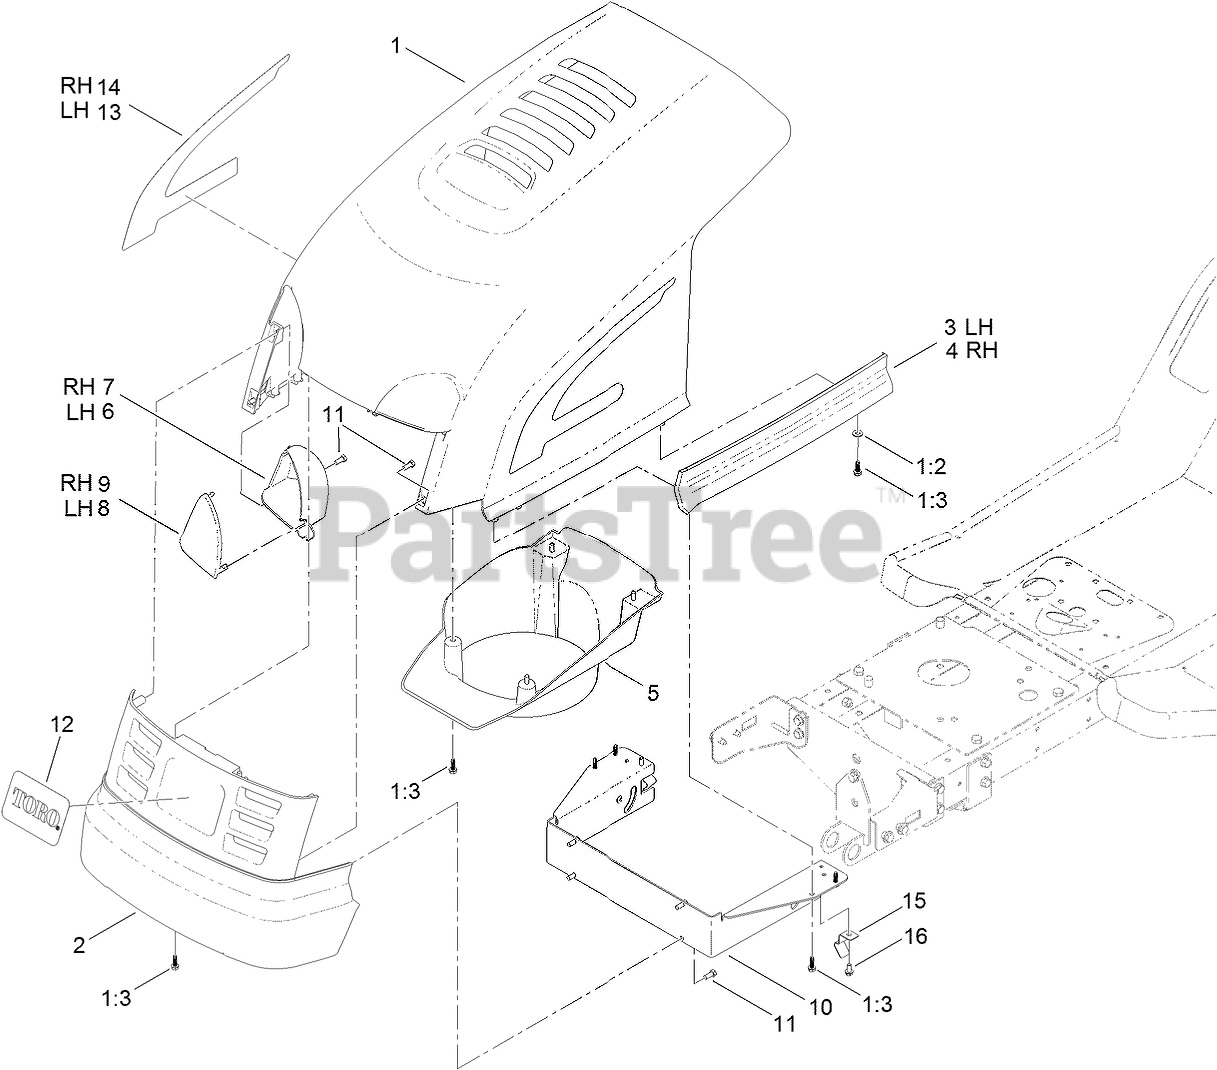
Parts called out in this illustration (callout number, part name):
1	HOOD KIT
1:2	WASHER-FLAT
1:3	SCREW-SELF TAPPING
3	TRIM-HOOD, LH
4	TRIM-HOOD, RH
5	DUCT-AIR, HOOD
6	REFLECTOR-LH
7	REFLECTOR-RH
8	LENS-LH
9	LENS-RH
10	BRACKET-MOUNTING, HOOD
11	SCREW-PLASTITE
13	DECAL-HOOD, LEFT
14	DECAL-HOOD, RIGHT
15	LATCH-HOOD
16	SCREW-HWH
